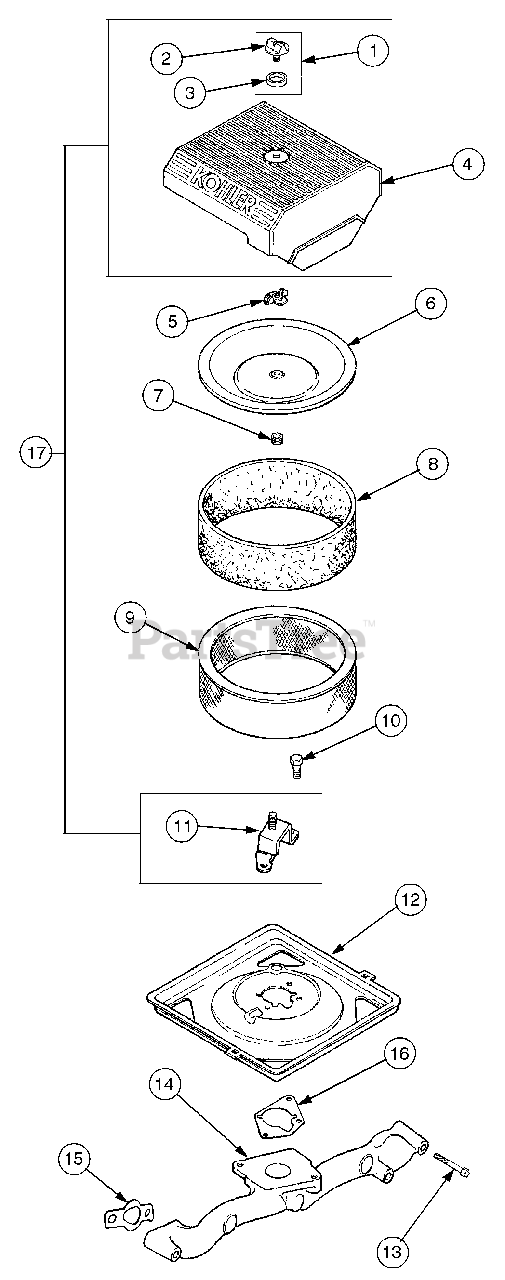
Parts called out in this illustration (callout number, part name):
1	Kit, Knob w/Seal
3	Seal, Air Cleaner Cover Knob
4	Cover, Air Cleaner
6	Cover, Inner Air Cleaner
7	Seal, Inner Air Cleaner
8	Precleaner, Element
9	Element, Air Cleaner
10	Screw, Hex Flange, M6 x 1.0 x 16
11	Bracket, Air Cleaner Base
12	Base, Air Cleaner
13	Screw, Hex Flange, M6 x 1.0 x 55
14	Manifold, Intake
15	Gasket, Intake Manifold
16	Gasket, Air Cleaner Base
17	Kit, Air Cleaner Cover
